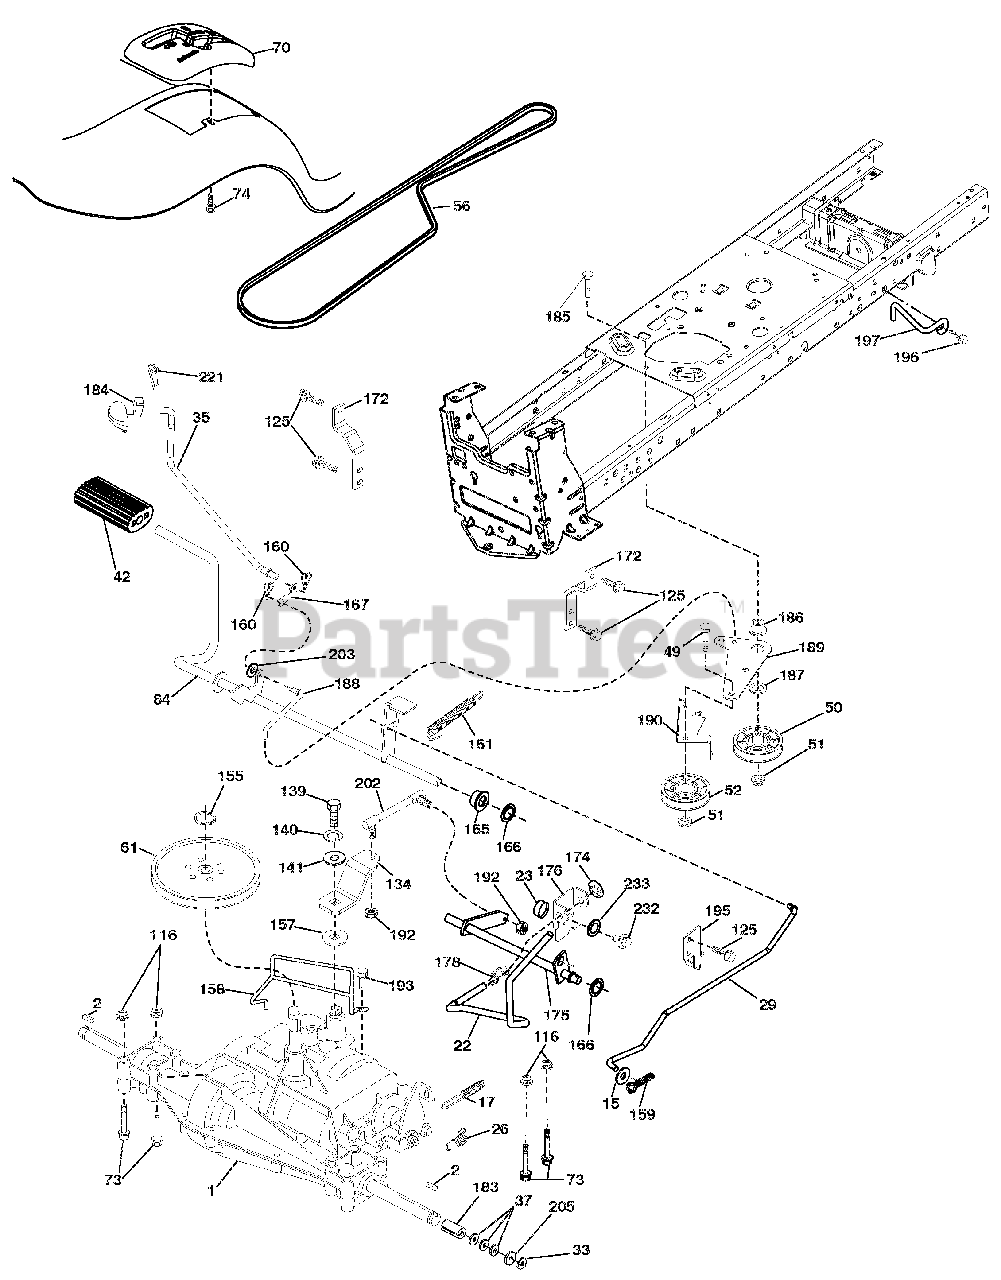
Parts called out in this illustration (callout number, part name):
1	TRANSAXLE, PEERLESS 206-565(197941) (ORDER PARTS FROM TRANSAXLE MANUFACTURER.)
2	KEY.SQUARE.2.0 X .1845/.1865
15	WASHER.13/32 X 13/16 X 16 GA.
17	SPRING.BRAKE.PEERLESS/D6800.TX
22	ROD.SHIFT.FENDER.TLT.2006
26	SPRING.BRAKE.RTN.GR DR.TEX.006
29	ROD.BRAKE.PEERLESS/D6800
33	E-RING.#5133-75
35	ROD, BRAKE, PARK
37	WASHER.25/32 X 1 1/4 X 16 GA.
42	COVER PEDAL BLK ROUND
49	BOLT.RDHD.3/8-16UNCX1-3/4.GR5
50	IDLER.FLAT.910"OFFSET
51	Nut, Hex, Flangelock 3/8-16
52	IDLER.V-GROOVE.910"OFFSET
56	V-BELT.DRV.97.40"PMST/DANA
61	PULLEY.TRANSAXLE.18/20"TIRES
64	SHAFT ASM.PEDAL.BRAKE CONTROL
70	CONSOLE SHIFT
73	BOLT 5/16-18 X 2 1/2 G.5
74	SCREW.HEX.WSH.HI-LO.1/4X1/2UNC
116	Nut, Lock Hex Flange 5/16-18 u
125	SCREW.5/16-18X3/4.SMGML.TAP/BL
134	ASM SHIFT
139	BOLT.1/4-28 UNF.GR8.W/PATCH
140	Washer, Lock 1/4
141	WASHER.9/32 X 3/4 X 10 GA.
155	Ring, Retainer
157	WASHER.PLATE.SHF..388 SQ.HOLE
158	KEEPER.T/A.PMS/D4360/D680.1820
159	PIN.COTTER.1/8 X 3/4.CAD.
160	RETAINER.CLIP(M).DIA.290
161	SPRING.RETURN.CLUTCH.6.75
165	BUSHING.SHAFT.BRAKE.HAND CONTR
166	NUT PUSH .625
167	LATCH.BRAKE.PARKING
172	STRAP.TRQ.LH.GEAR DRIVE.LT.TEX
174	NUT.PUSH..500
175	SHAFT ASM. SHIFT GEAR DRIVE
176	ARM.CLEVIS.ROD.SHIFT
178	SPRING.SHIFT.GT.2006
183	SPACER.AXLE.HYDRO/PEERLES
184	HANDLE PARKING BRAKE
185	BOLT.RDHD.3/8-16UNC X2-3/4 GR5
186	SPACER.RETAINER
187	WASHER.13/32 X 2 X 10 GA.
188	LINK.CLUTCH.GROUND DRIVE
189	BELLCRANK.GROUNDRIVE.NSTG/NSTL
190	KEEPER.BELLCRANK.DRIVE.GROUND
192	NUT.LOCK.CENTER.1/4-28 FNTHD.
193	SCREW.5/16-18X3/4.SMGML.TAP/R
195	BRACKET.ROD.BRK.PEERLESS/D6800
196	SCREW.3/8-16X1.SMGML.TAP/R.BLK
197	LINK CLUTCH ANTI-ROTATION
203	Washer 11/32 x 11/16 x 16 Ga.
205	WASHER.25/32 X 1-5/8 X 16GA.
221	RETAINER.SPRING.CLIP.HANDLE
232	BOLT.FIN HEX.7/16-14X1 GR5
233	WASHER.SERRATED
